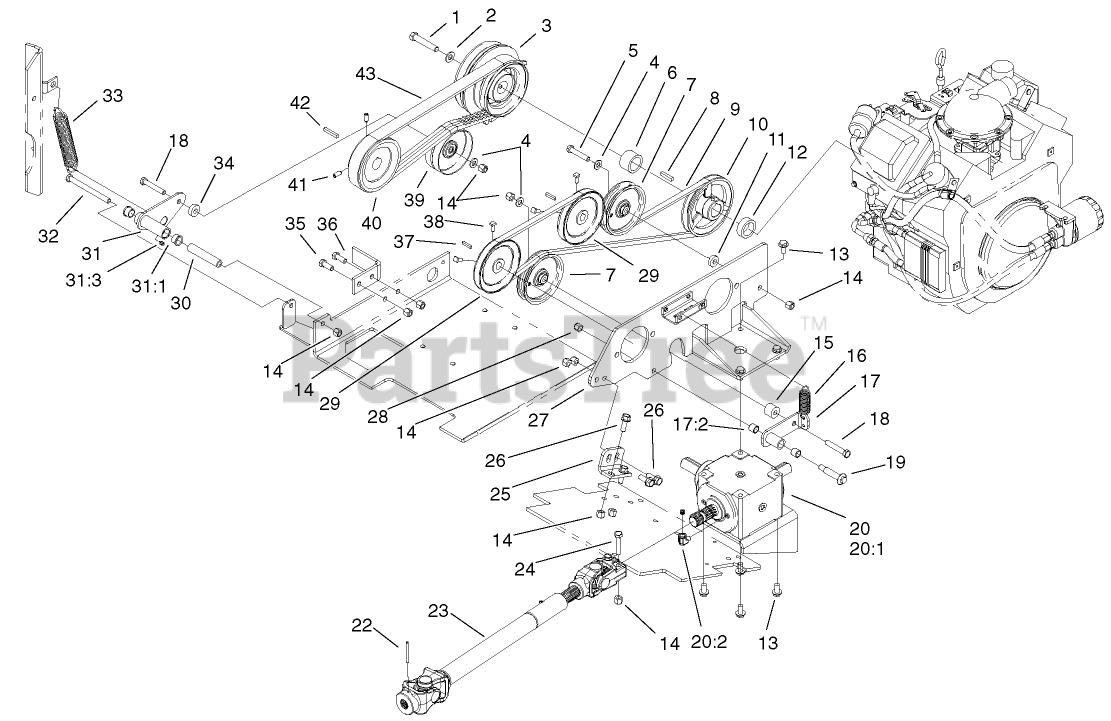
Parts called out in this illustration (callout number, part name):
1	SCREW-HH
2	WASHER-FLAT
3	CLUTCH
4	WASHER-FLAT
5	SCREW-HH
6	SPACER-SHAFT, ENGINE
7	PULLEY-IDLER
8	KEY-SQUARE
9	V-BELT
10	PULLEY-ENGINE
11	Washer
12	SPACER-SHAFT, ENGINE
13	SCREW-HHF
14	NUT-LOCK, NI
15	SPACER-ARM, IDLER
16	SPRING-EXTENSION
17	IDLER ARM ASM
17:2	BUSHING
18	SCREW-HH
19	BOLT-WHEEL
20	GEARBOX ASM
20:1	Gearbox-PTO
20:2	ELBOW
22	PIN-SPRING
23	SHAFT-DRIVE
24	SCREW-HH
25	MOUNT-PLATE, PUMP
26	SCREW-HHF
27	PUMP MOUNT ASM
28	NUT-LOCK
29	PULLEY-PUMP, TRACTION
30	SPACER-IDLER
31	IDLER ARM ASM
31:1	BUSHING
31:3	FITTING-STRAIGHT
32	SCREW-HH
33	SPRING-EXTENSION
34	SPACER-IDLER
35	SCREW-HH
36	STOP-CLUTCH
37	KEY-PUMP
38	SCREW-SET
39	PULLEY-FLAT
40	PULLEY-CLUTCH
41	SCREW-SET, HSH
42	KEY-SQUARE
43	BELT-V, BANDED
